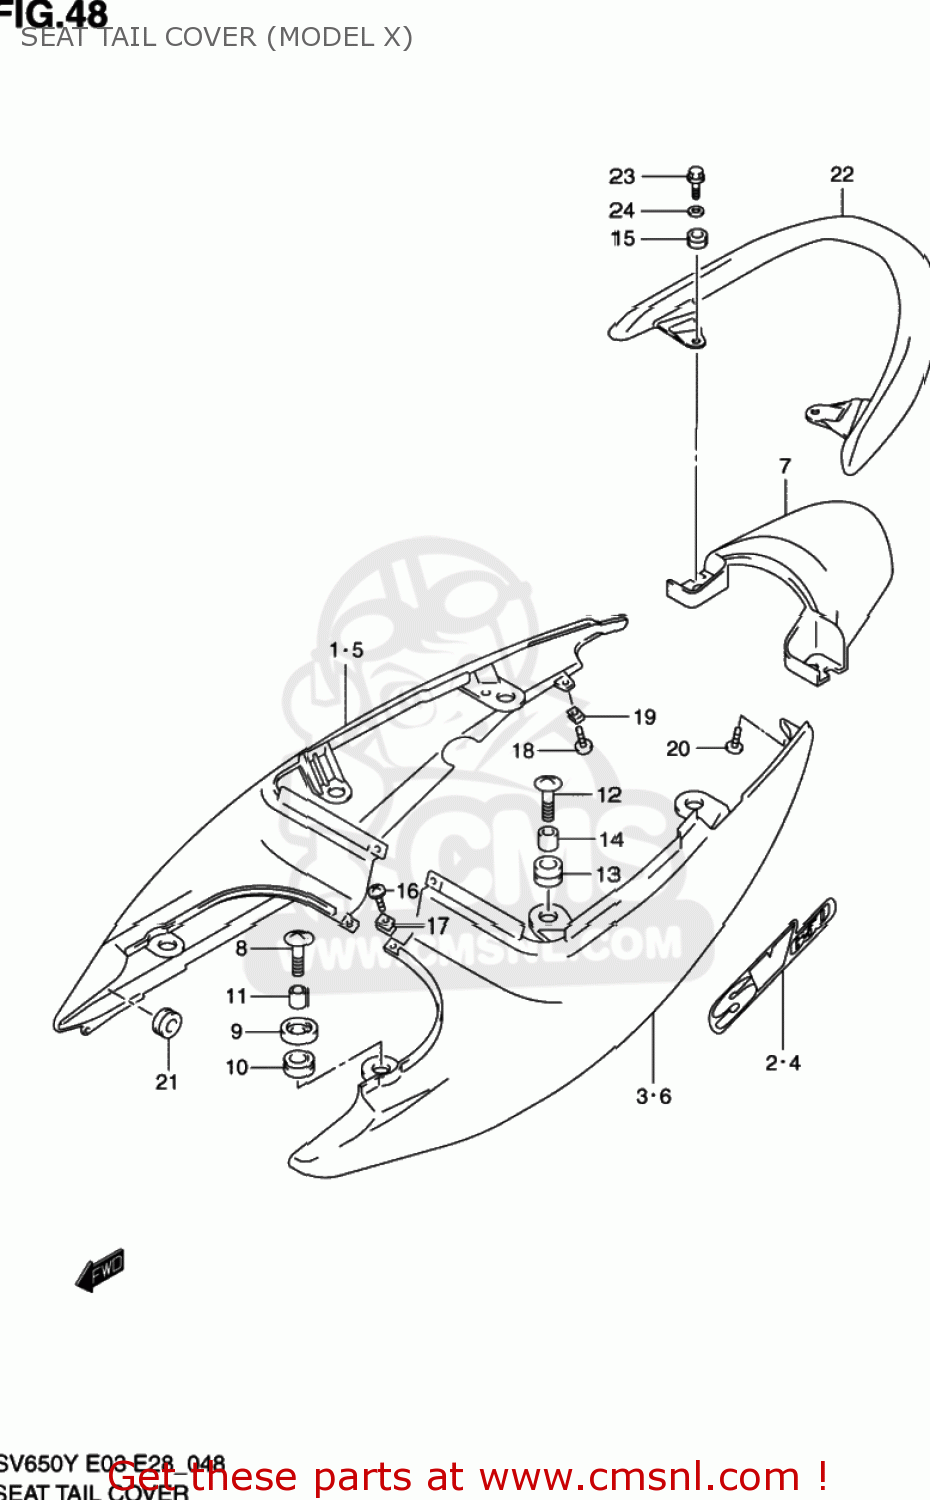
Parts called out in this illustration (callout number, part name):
1	COVER,SEAT TAIL,R(RED)
2	EMBLEM,SEAT TAIL COVER SV650
3	COVER,SEAT TAIL,L(BLUE)
4	EMBLEM,SEAT TAIL COVER SV650
5	COVER SEAT TAIL R
6	COVER SEAT TL,
7	COVER,SEAT TAIL CTR
8	SCREW(6X30)
9	CUSHION,SEAT TAIL FR UPR
10	CUSHION,SEAT TAIL COVER FR
11	SPACER(6.5X10X15.7)
12	SCREW(6X20)
13	CUSHION
14	SPACER(6.5X10X9.4)
15	CUSHION,SEAT TAIL COVER RR
16	SCREW
17	NUT
18	SCREW
19	NUT
20	SCREW
21	CUSHION
22	HANDLE,PILLION RIDER(BLACK)
23	BOLT
24	WASHER(8.5X20X2.6)
